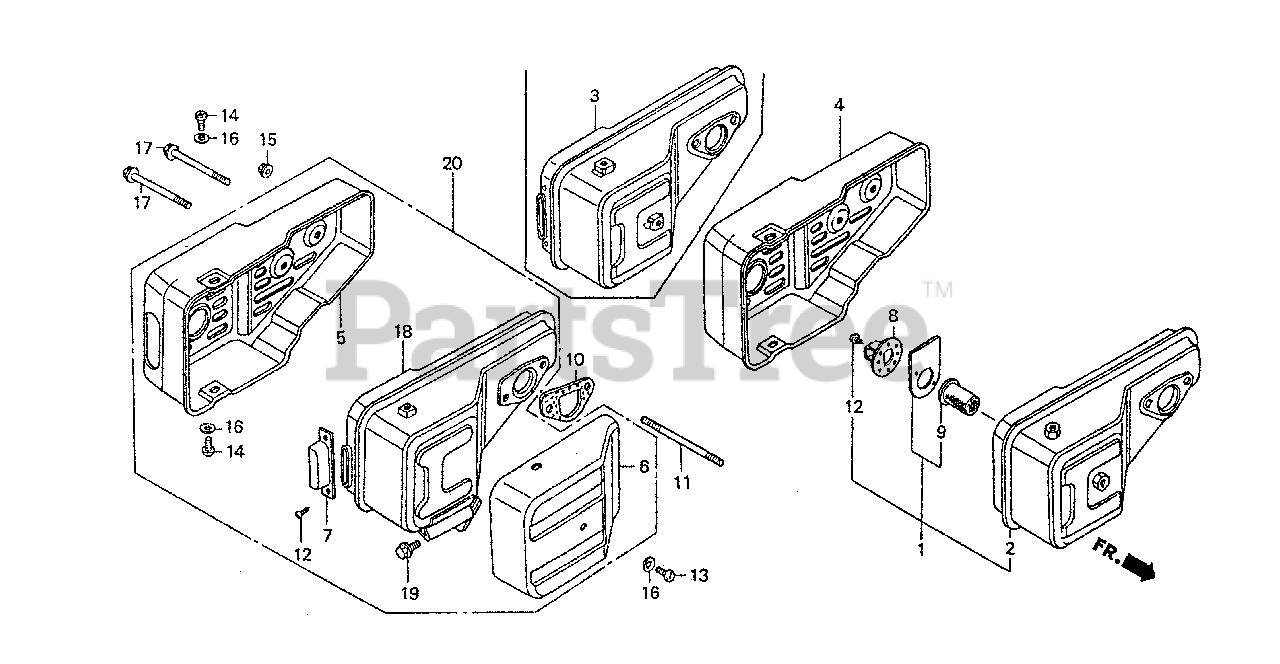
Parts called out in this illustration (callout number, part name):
2	MUFFLER (W/PROTECTOR)
4	PROTECTOR, MUFFLER
6	SEPARATOR, MUFFLER
8	DEFLECTOR, MUFFLER
10	GASKET, MUFFLER
11	BOLT, STUD (6X50)
12	SCREW, TAPPING (4X8)
14	SCREW, PAN (6X6)
15	NUT, FLANGE (6MM)
20	MUFFLER ASSY.
